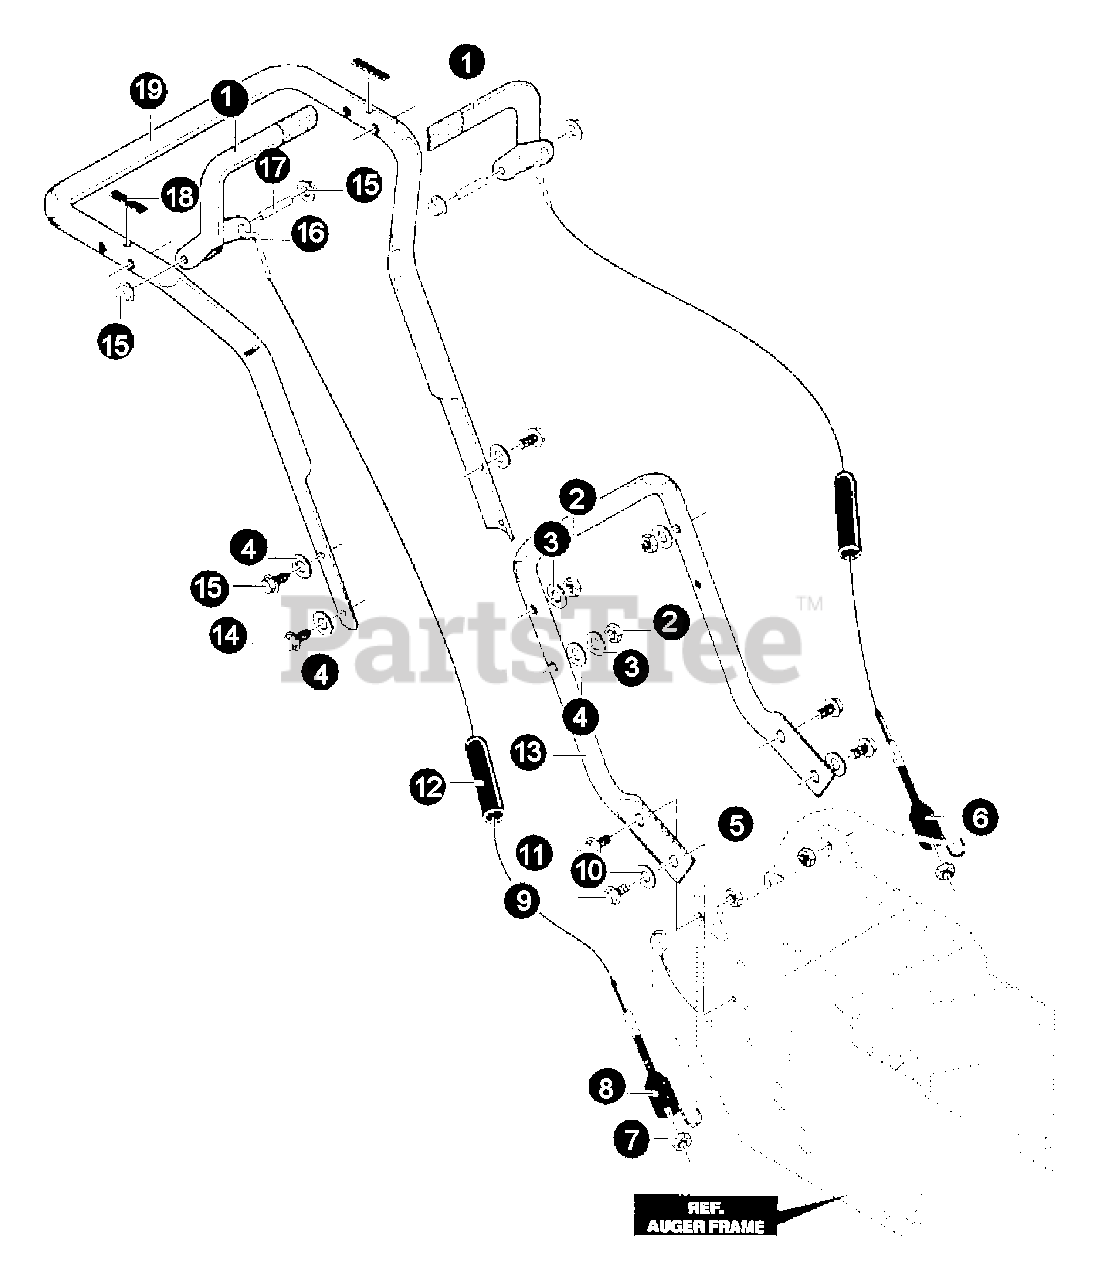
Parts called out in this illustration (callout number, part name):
1	CLUTCH HANDLES SET
2	NUT, 3/8"-16
3	WASHER. REGSPTLK 0.393×0.68×0.10
4	WASHER
5	NUT, 5/16"-18
6	SPRING
7	NUT, 1/4"-20
8	SPRING, AUGER CLUTCH
9	SCREW, 5/16-18×0.50 WAHHTAP
10	WASHER
11	SCREW, 5/16-18×0.75 WAHHTAP
12	BOOT, CLUTCH SPRING
13	HANDLE, LOWER
14	SCREW - 3/8-16×2.00"
15	NUT, PUSH
16	CABLE, CLUTCH
17	PIN, PIVOT CLUTCH
18	BUMPER, RECT
19	HANDLE, UPPER
